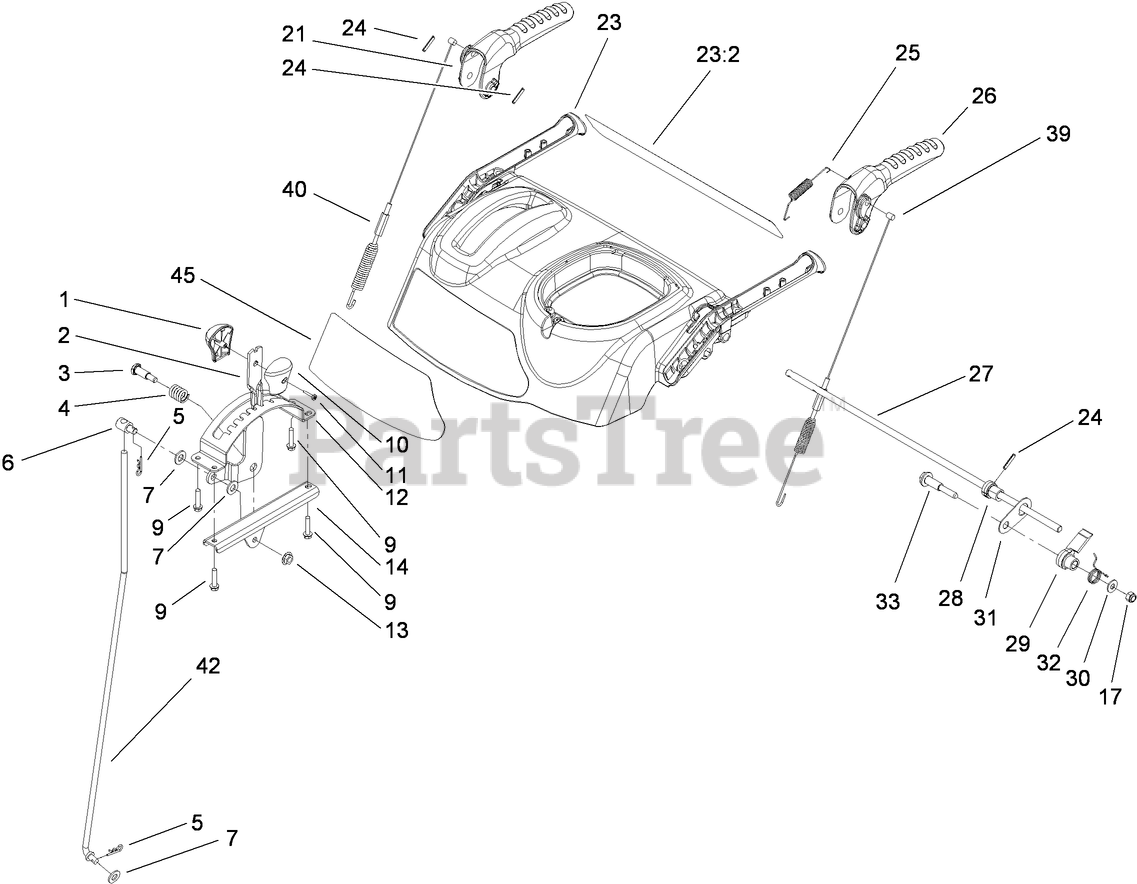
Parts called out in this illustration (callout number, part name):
1	KNOB-SHIFT, RH
2	SELECTOR-SPEED
3	SCREW-SHOULDER
6	TRUNNION-ROD
7	WASHER-FLAT
9	SCREW-PLASTITE
10	KNOB-SHIFT, LH
11	SCREW-PPH
12	GUIDE-SELECTOR, SPEED
13	NUT-HF
14	MOUNT-SELECTOR, SPEED
17	NUT-LOCK, NI
21	LEVER-AUGER
23	CONTROL PANEL ASM
23:2	DECAL-PANEL, CONTROL
24	PIN-SPRING
25	SPRING-TENSION
26	LEVER-TRACTION
27	ROD-LOCKOUT
28	CAM-LOCKOUT
29	LATCH-LOCKOUT
30	WASHER-FLAT
31	LINK-LOCKOUT
32	SPRING-TORSION
40	CABLE-AUGER
45	DECAL-CONTROL PANEL
